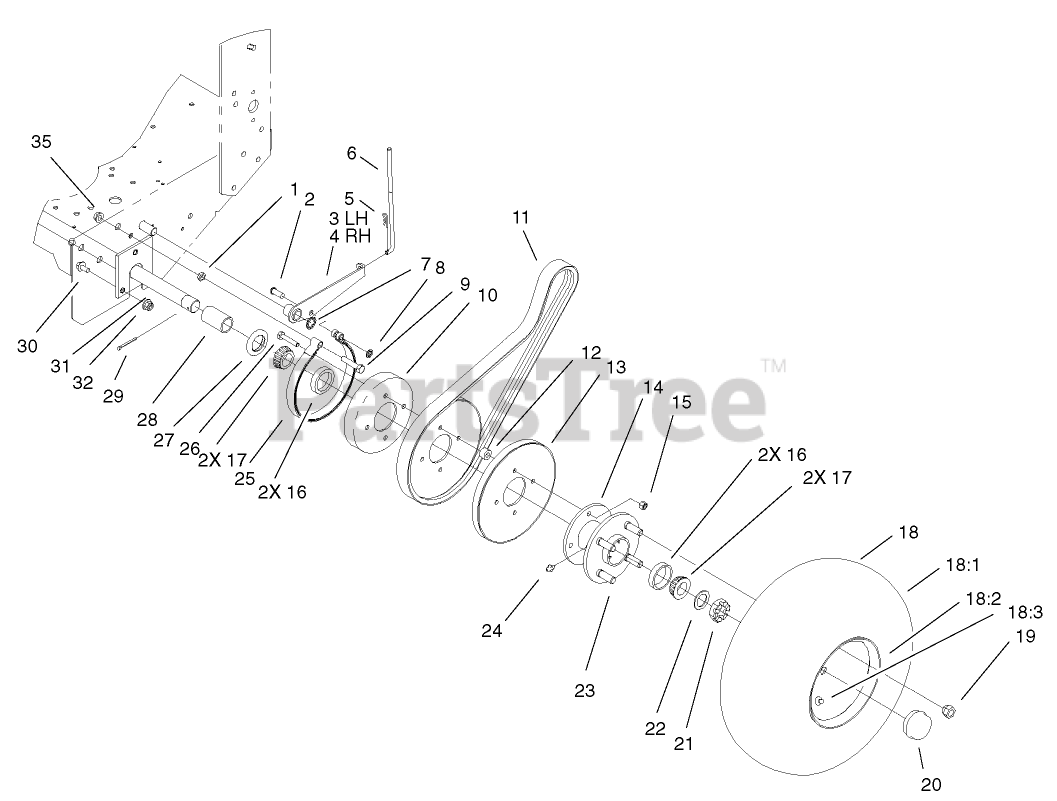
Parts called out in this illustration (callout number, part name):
1	NUT-JAM
2	PIN-CLEVIS
3	ARM-BRAKE, LH
4	ARM-BRAKE, RH
5	PIN-COTTER
6	ROD-BRAKE
7	RING-RETAINING
8	RING-RETAINING, EXTERNAL
9	SCREW-HH
10	DRUM-BRAKE
11	BELT-DRIVE, TRACTION
12	SPACER-PULLEY
13	PULLEY-WHEEL
14	HUB/WHEEL ASM
15	NUT-LOCK, NI
16	BEARING-CUP, TAPERED
17	BEARING-CONE, TAPERED
18	WHEEL AND TIRE ASM
18:2	WHEEL
18:3	STEM-VALVE
19	NUT-LUG
20	CAP-DUST
21	NUT-SHH
22	WASHER-SPACER
23	STUD-WHEEL
24	FITTING-GREASE
25	BAND-BRAKE
26	SCREW-HH
27	SEAL-GREASE
28	SPACER-WHEEL
29	PIN-COTTER
30	SCREW-HHF
31	AXLE ASM
32	NUT-HF
35	NUT-HHF, WHIZ
